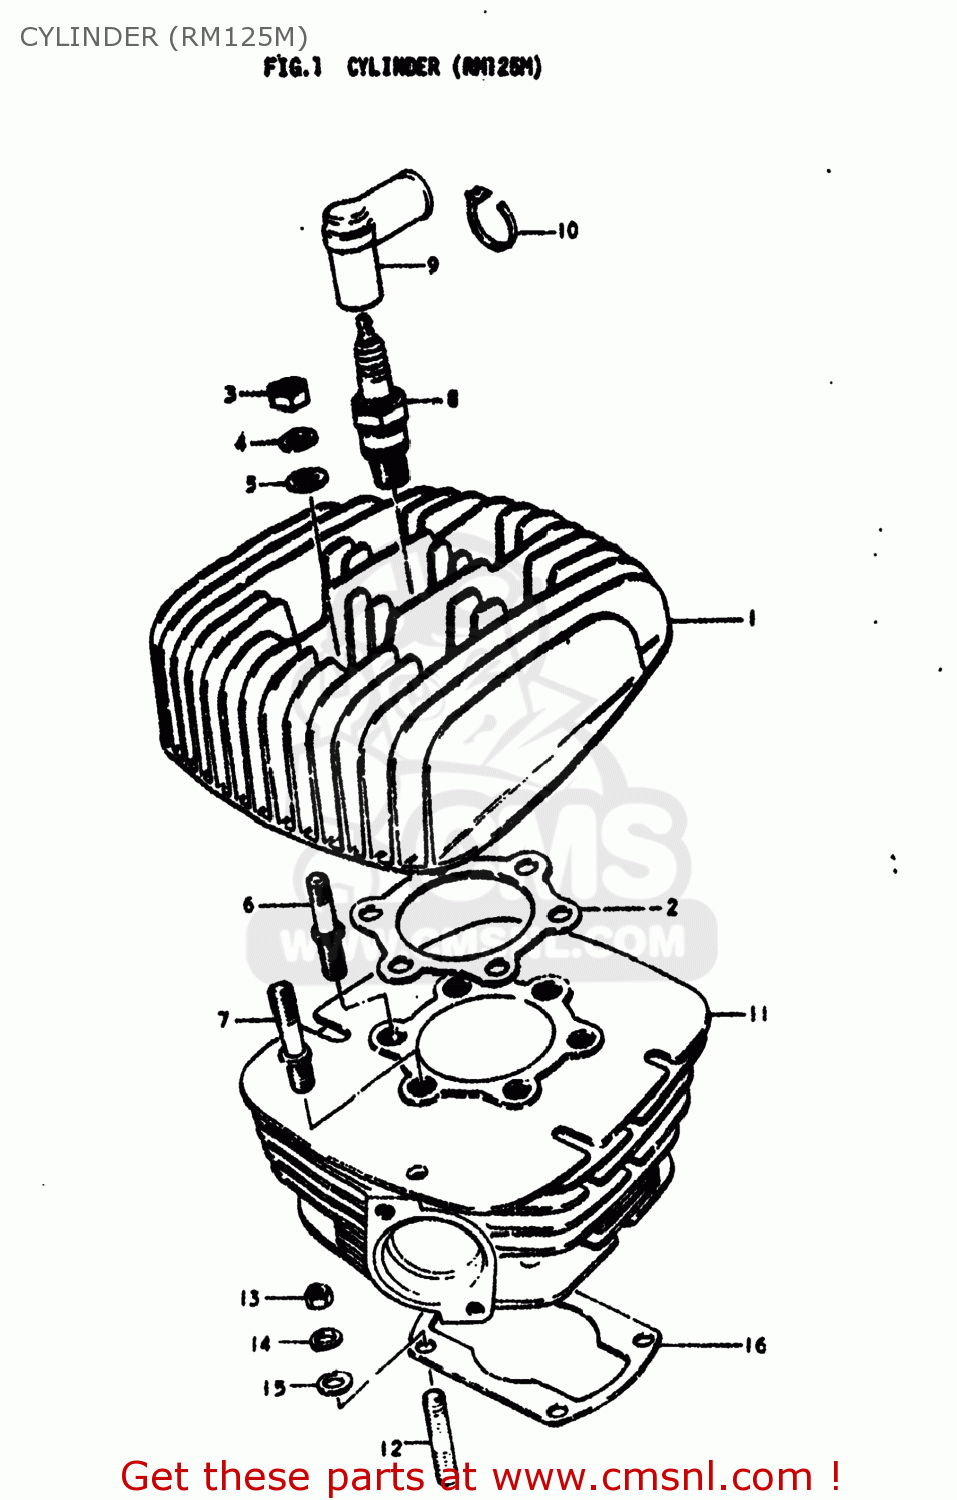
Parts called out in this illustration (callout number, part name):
1	HEAD,CYLINDER
2	GASKET,CYLINDER HEAD (MCA)
3	NUT (8MM)
4	LOCK WASHER
5	WASHER
6	BOLT,STUD
7	STUD
8	SPARK PLUG
9	CAP,SPARK PLUG
10	CLAMP
11	CYLINDER
12	STUD 8X25
13	NUT
14	LOCK WASHER
15	WASHER
16	GASKET,CYLINDER (MCA)
